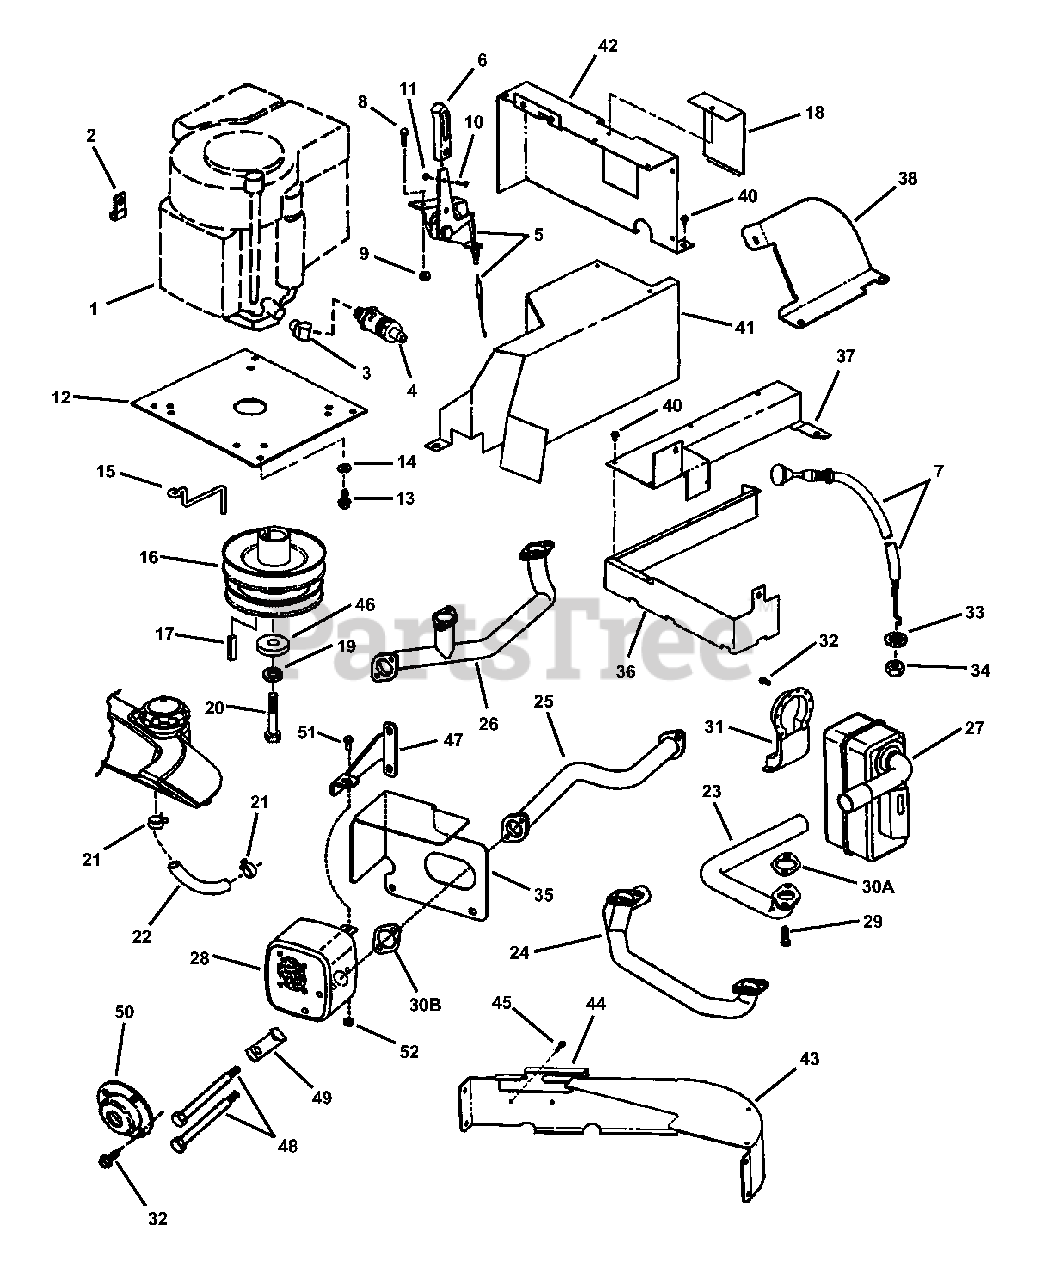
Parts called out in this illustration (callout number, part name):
1	ENGINE, 15 HP Kohler
2	WIRE CLIP, 7/16"
3	FITTING, Oil Drain Short
4	ASSEMBLY, Oil Valve
5	CONTROL, Throttle (52.5" conduit length)
6	LEVER, Throttle Control
7	CONTROL CABLE, Choke
8	SCREW, #10-32 x 5/8" Hex Washer Head, Grade 5
9	NUT, #10-32 Nyloc
10	SCREW, #8-32 x 3/8" Machine
11	NUT, #8-32 Hex
12	PLATE, Engine
13	SCREW, 3/8-16 x 1" Hex Washer Head
14	WASHER, 5/16 Split Lock
15	GUIDE, Belt
16	PULLEY, Engine
17	KEY, 1/4" Square x 2"
18	COVER, Spark Plug Access
19	WASHER, 7/16" Split Lock
20	SCREW, 7/16-20 x 1-1/2" Hex Head Cap, Grade 5
21	CLAMP, Fuel Hose
22	HOSE, Fuel 1/4" I.D. x 20"
23	PIPE, Exhaust
24	PIPE, Exhaust
25	MANIFOLD, Briggs 16HP Intek
26	MANIFOLD, Briggs 20HP Intec
27	MUFFLER
28	MUFFLER, Briggs 16HP & 20HP
29	SCREW, 5/16-18 x 3/4" Hex Head Cap, Grade 5
30A	GASKET, Exhaust
30B	GASKET, Exhaust
31	DEFLECTOR, Muffler (42" Deck only)
32	SCREW, #8-18 x 1/2"
33	WASHER, 3/8" Internal Tooth Lock
34	NUT, 3/8-24 Hex
35	HEAT SHIELD, Muffler
36	HEAT SHIELD, Sides
37	HEAT SHIELD, Top
38	HEAT SHIELD, Starter
40	SCREW, #10-32 x 3/8" Sheet Metal
41	DUCT, Right Hand
42	DUCT, Front
43	DUCT, Air
44	SHIELD, Engine Speed Control Heat
45	SCREW, #10-32 x 3/8" Self Tapping
46	SPACER, Clutch
47	STRAP, Muffler, Briggs 16HP Intek
48	BOLT, 5/16-18 x 4" Shoulder
49	SCREW LOCK
50	DEFLECTOR, Direct Out
51	SCREW, 1/4-20 x 5/8" Hex Head Cap, Grade 5
52	NUT, 1/4-20 Hex Flange Lock, Grade 5
